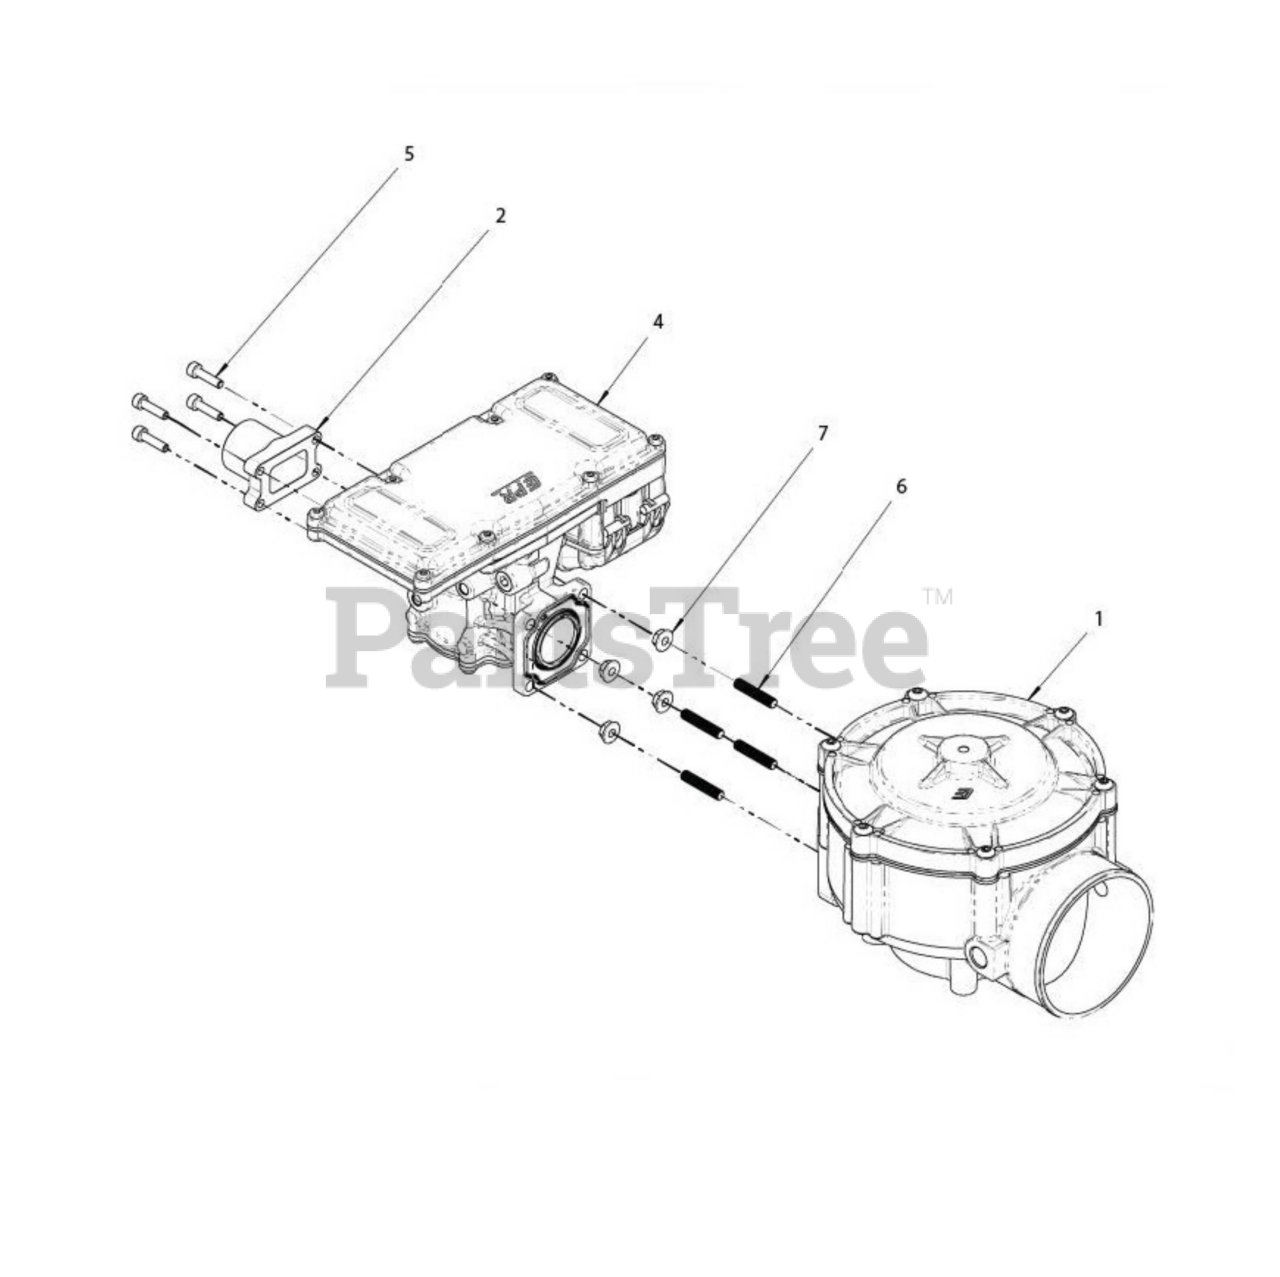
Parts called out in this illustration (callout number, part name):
1	*MIXER
3	*SCREW
4	PROGRAMMED EPR
5	*BOLT
6	*STUD
7	*NUT
